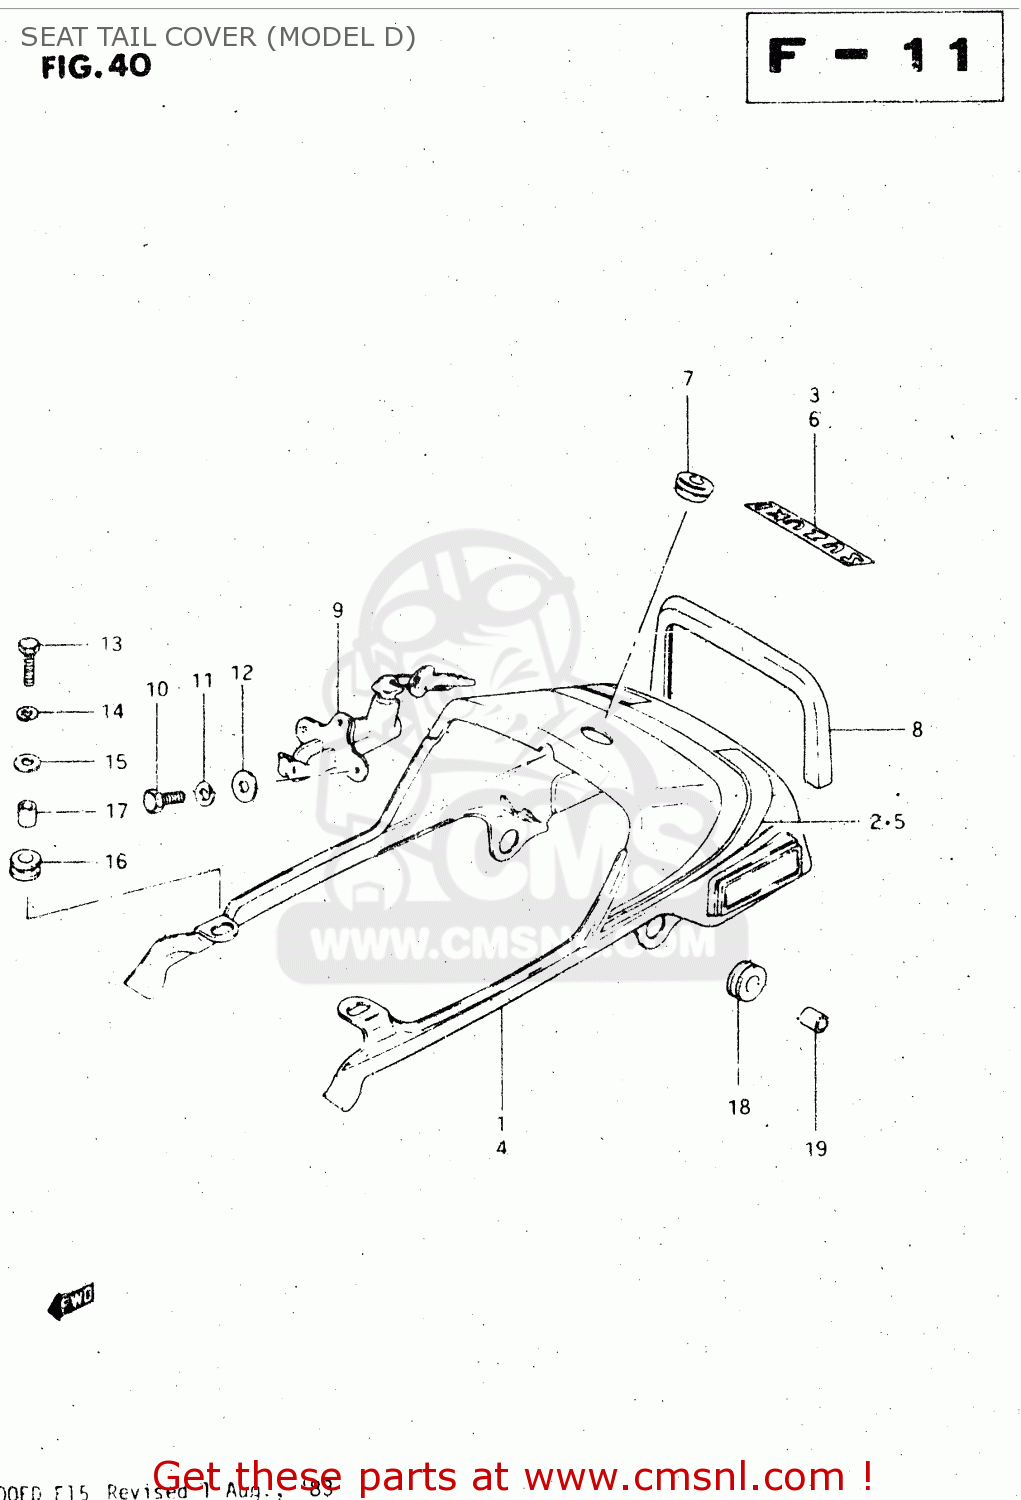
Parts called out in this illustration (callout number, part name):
1	COVER, SEAT TAIL (RED)
2	TAPE, SEAT TAIL COVER
3	EMBLEM,SEAT TAIL COVER
4	COVER, SEAT TAIL (BLUE)
5	TAPE, SEAT TAIL COVER
6	EMBLEM
7	GROMMET,SEAT LOCK HOLE
8	GROMMET
9	LOCK SET,SEAT
10	BOLT
11	LOCK WASHER
12	WASHER
13	BOLT
14	LOCK WASHER
15	WASHER(6,5X22X1.6)
16	CUSHION
17	SPACER(6.5X10.5X12)
18	CUSHION
19	SPACER
